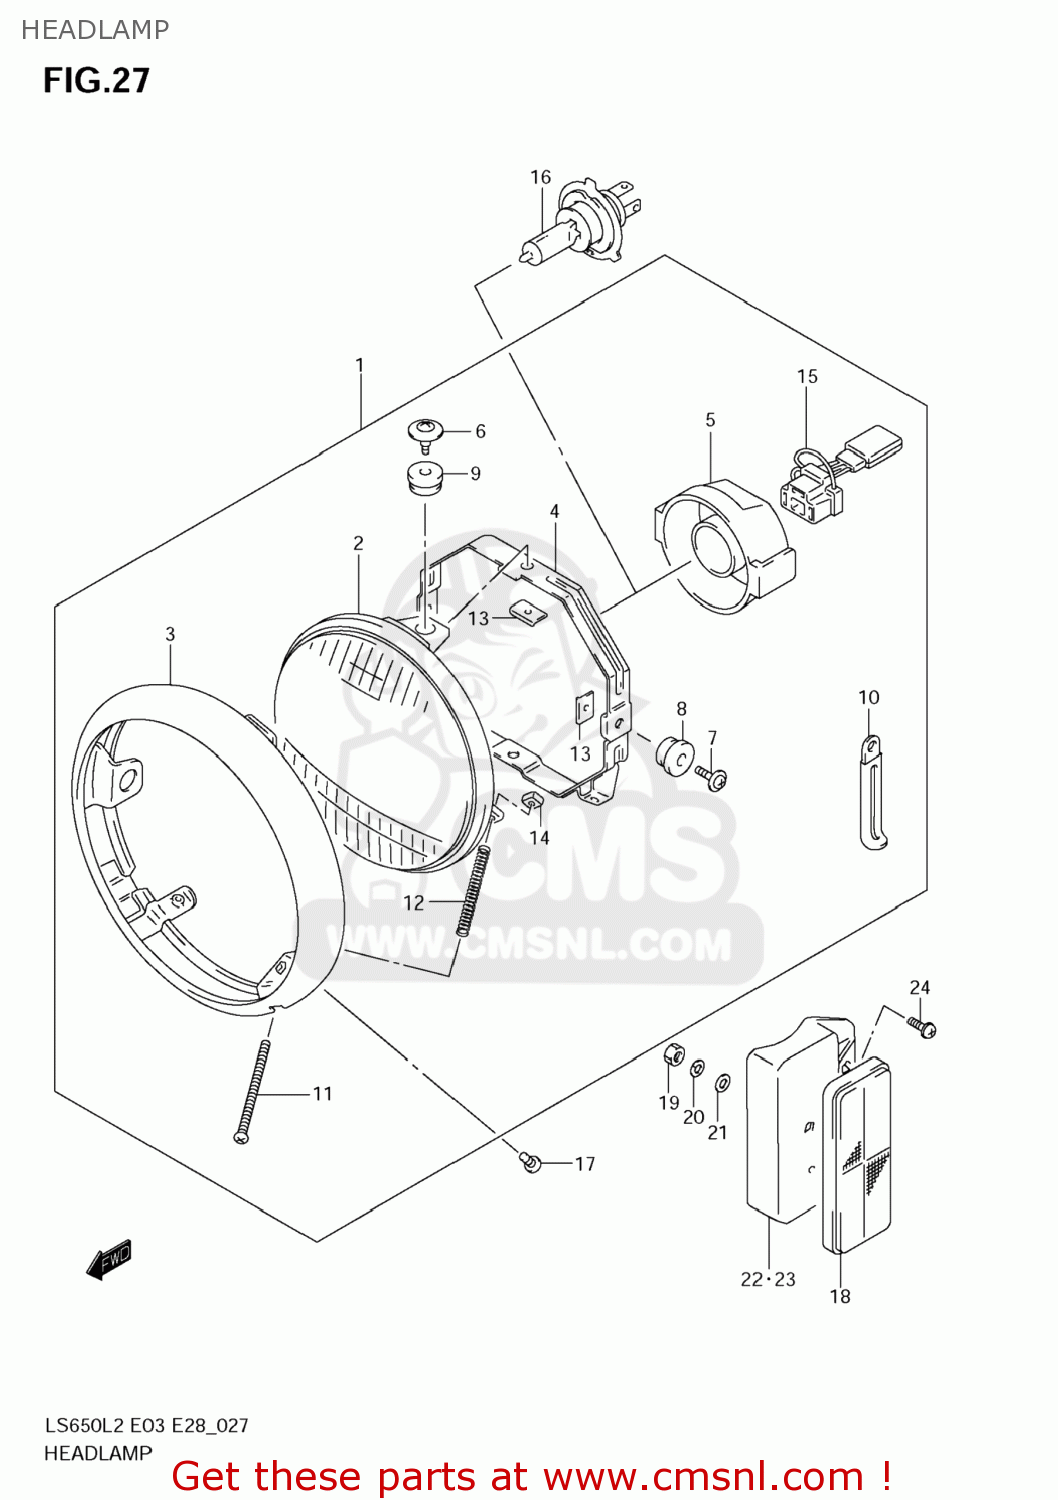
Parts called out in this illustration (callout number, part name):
1	HEADLAMP ASSY
2	UNIT,LAMP
3	RIM
4	RING,MOUNTING
5	COVER
6	SCREW
7	SCREW,MOUNTING
8	CUSHION
9	CUSHION
10	CLAMP(L:65)
11	SCREW,ADJUSTING(4X50)
12	SPRING
13	NUT
14	NUT,HEADLAMP ADJUST
15	SOCKET
16	BULB(12V60/55W,H4)
17	SCREW
18	REFLEX REFLECTOR,FR SIDE
19	NUT
20	WASHER,LOCK
21	WASHER(5.5X16X1.2)
22	BRACKET,FR SIDE RR,R
23	BRACKET,FR SIDE RR,L
24	SCREW(5X12)
